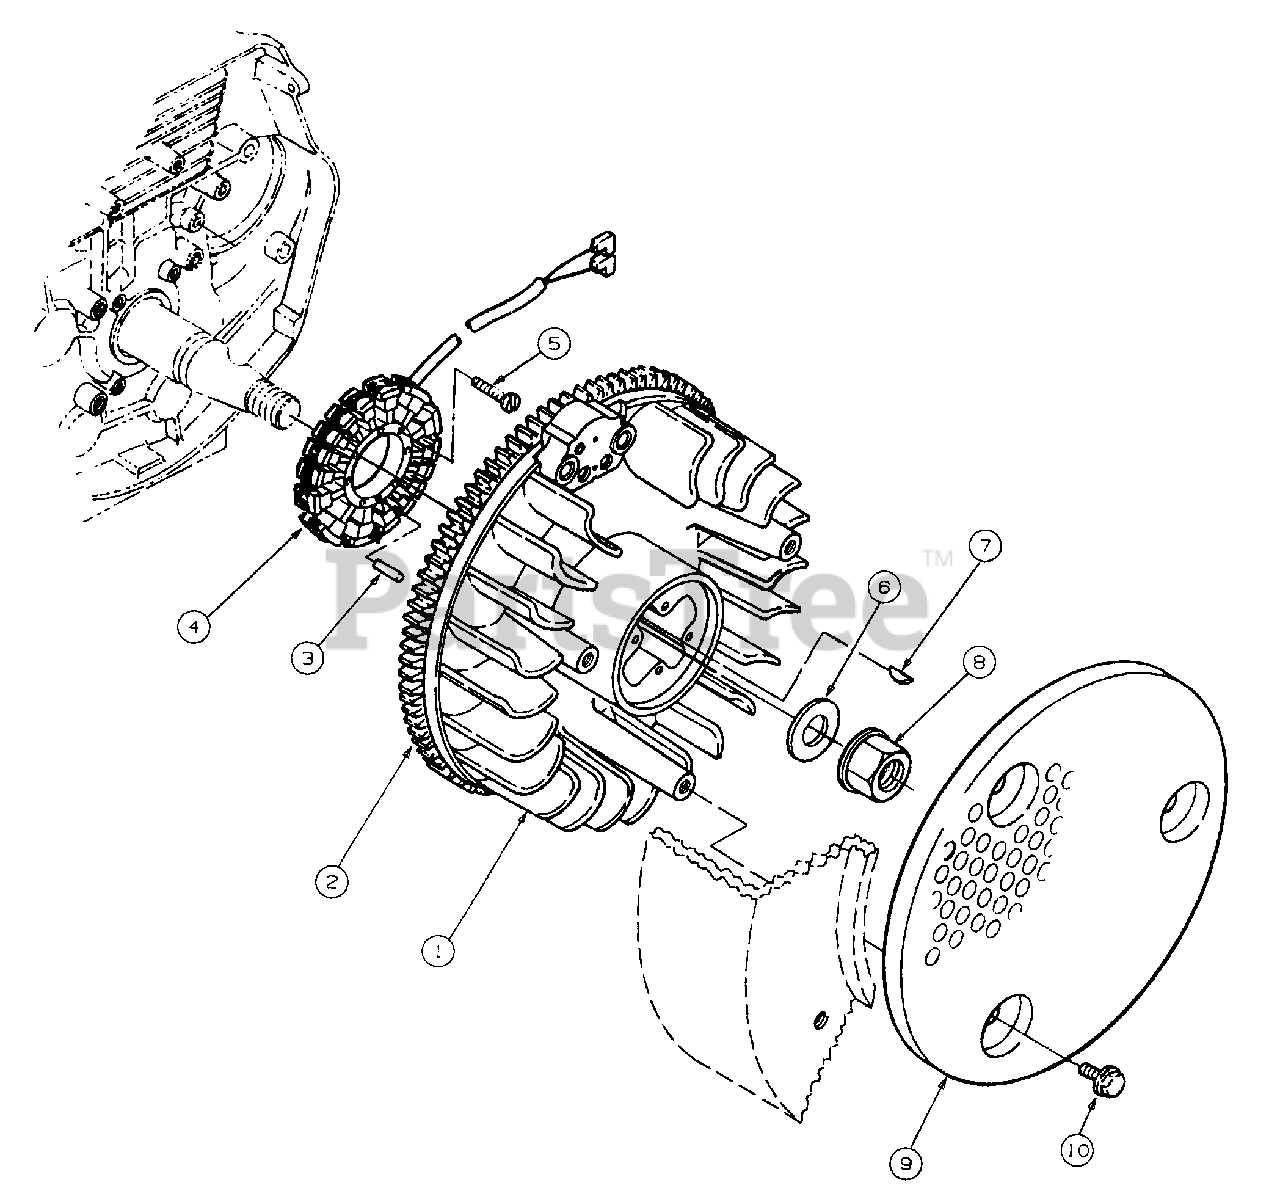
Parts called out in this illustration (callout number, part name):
1	Wheel Assy, Blower
3	Pin, Alignment
5	Screw, Button Head Machine, M6 x 1 x 20 mm
6	Washer, Flat, M18
8	Nut, Flange, M18 x 1.5 mm
9	Screen, Chaff
10	Screw, Hex Head Cap M6 x 1 x 1 0 mm
